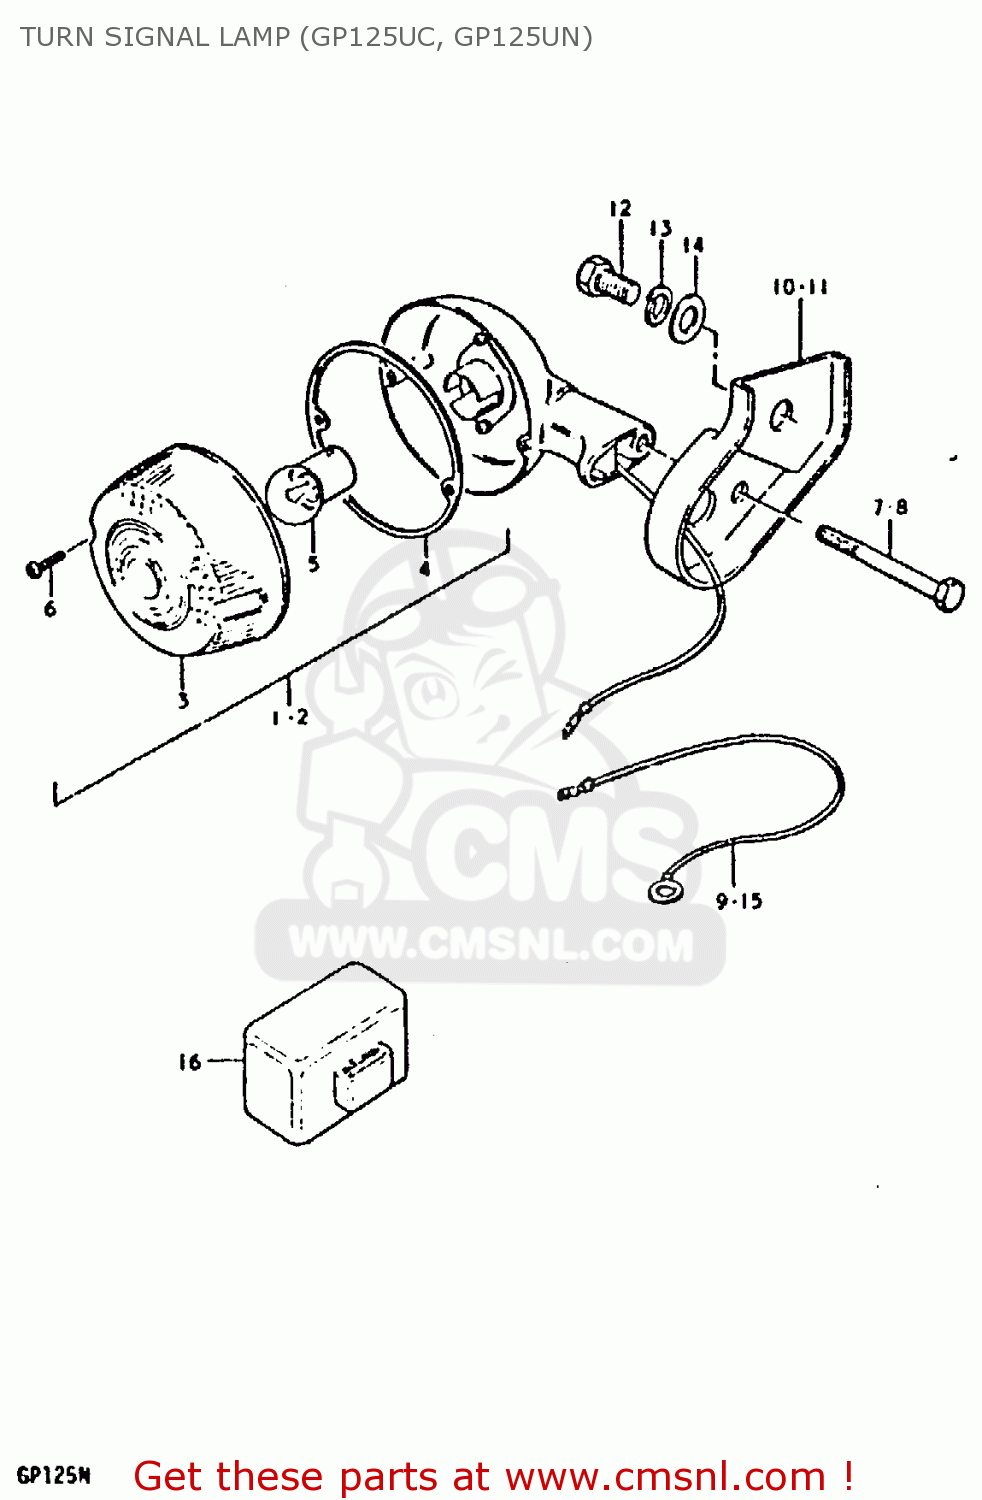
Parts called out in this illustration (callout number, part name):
7	BOLT, FRONT
8	BOLT 6X60
9	LEAD WIRE, FRONT ARTH
10	BRACKET, REAR TURN SIGNAL RH
11	BRACKET, REAR TURN SIGNAL LH
12	BOLT
13	LOCK WASHER
14	WASHER
15	LEAD WIRE, REAR EARTH
